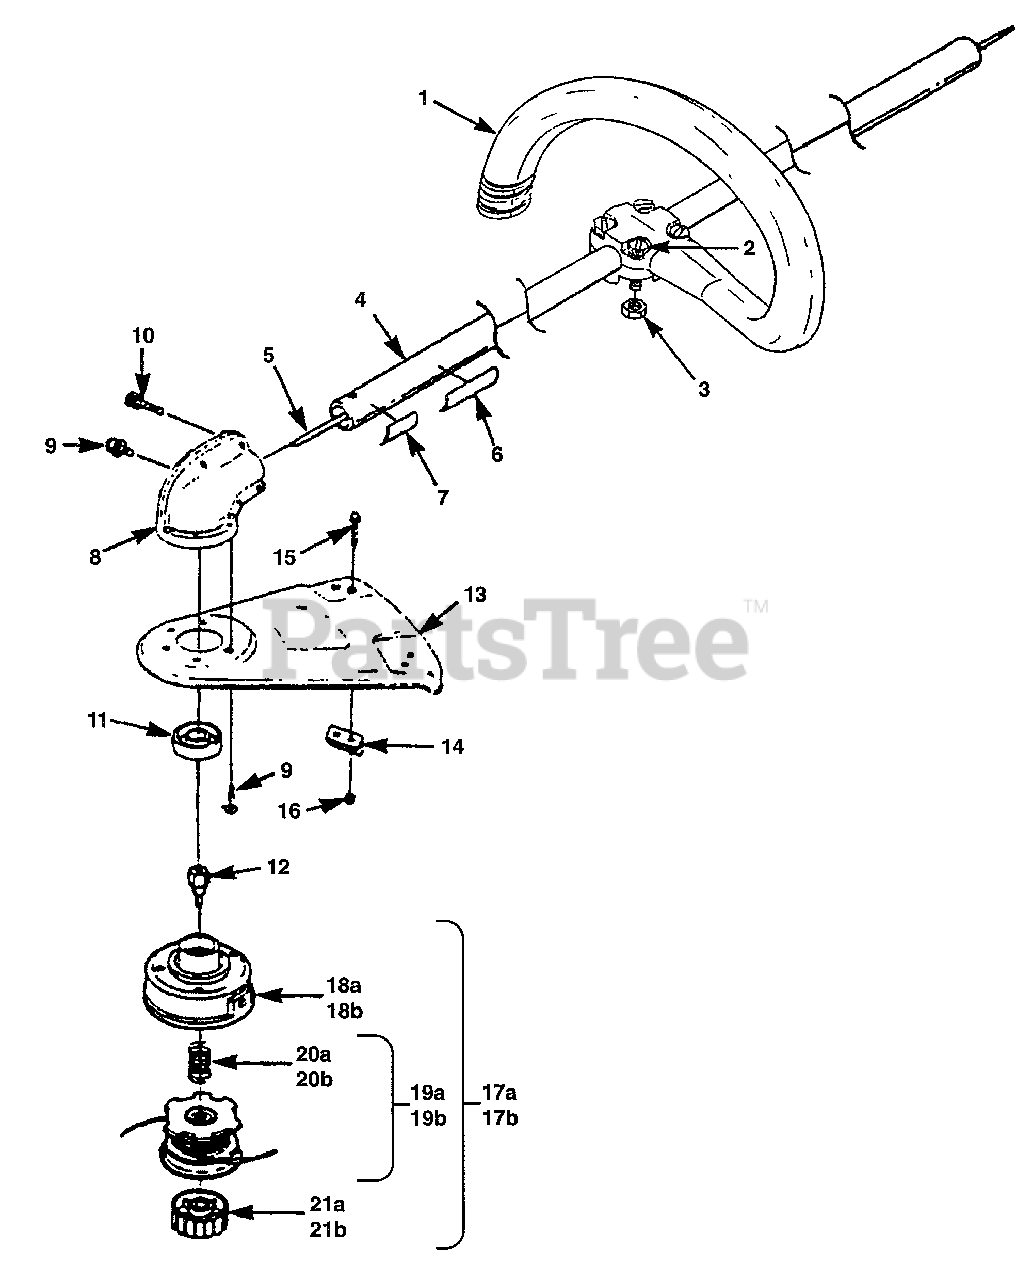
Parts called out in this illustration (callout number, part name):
1	FRONT HANDLE ("G")
2	SCREW-Hex Hd. (10-24 X 1")
3	NUT-Hex (10-24)
4	HOUSING-Drive Shaft
5	SHAFT-Flexible
6	DECAL-Starting Inst.
7	DECAL-Warning
8	GEAR HEAD
9	SCREW-Hex Hd. (10-24 X 1/2")
10	SCREW-Hex Hd. (10-24 X 5/8")
11	WASHER-Flanged
12	ADAPTOR-Shaft
13	GRASS DEFLECTOR KIT
14	BLADE-Cut-Off
15	SCREW-Machine Hex Hd. (10-24 X 3/8")
16	NUT-Hex (10-24)
17A	STRINGHEAD COMPLETE (.080" Line)
17B	STRINGHEAD COMPLETE (.095" Line)
18A	HOUSING & EYELET (Dual Line)
18B	HOUSING & EYELET (Dual Line)
19A	SPOOL & STRING & SPRING(.080" Line)
19B	SPOOL & STRING & SPRING (.095" Line)
20A	SPRING-Compression
20B	SPRING-Compression
21A	RETAINER-Spool (R.H. Thread, Black)
21B	RETAINER-Spool (R.H. Thread, Black)
